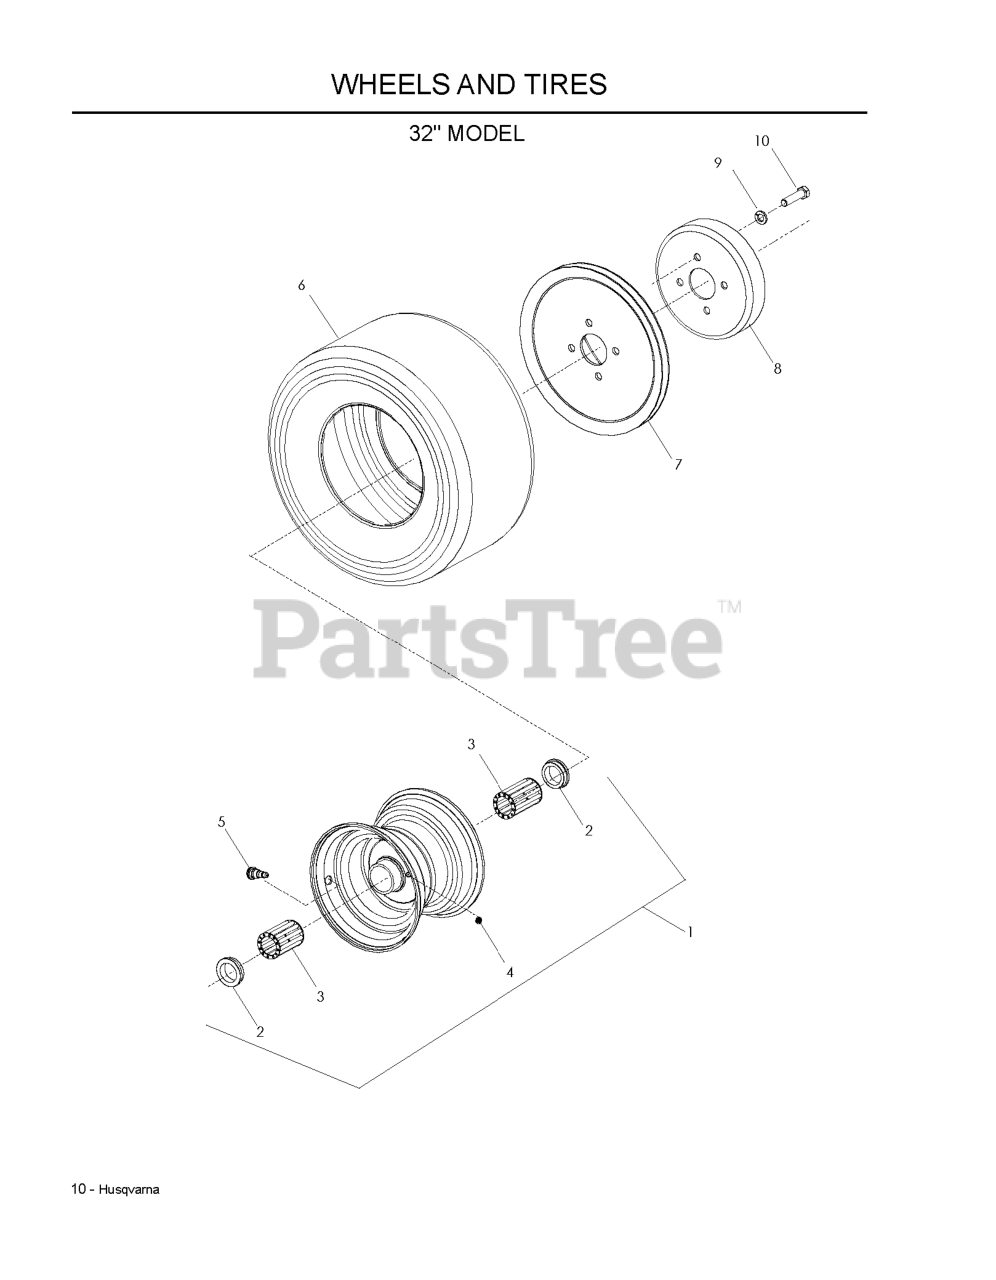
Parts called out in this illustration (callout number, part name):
2	BEARING FLANGE
3	ROLLER BEARING (LONG)
4	ZERK
5	VALVE STEM TR-412
7	TRACTION PULLEY
8	BRAKE DRUM
9	SLW 3/8 STD
10	HCS 3/8F X 3/4
